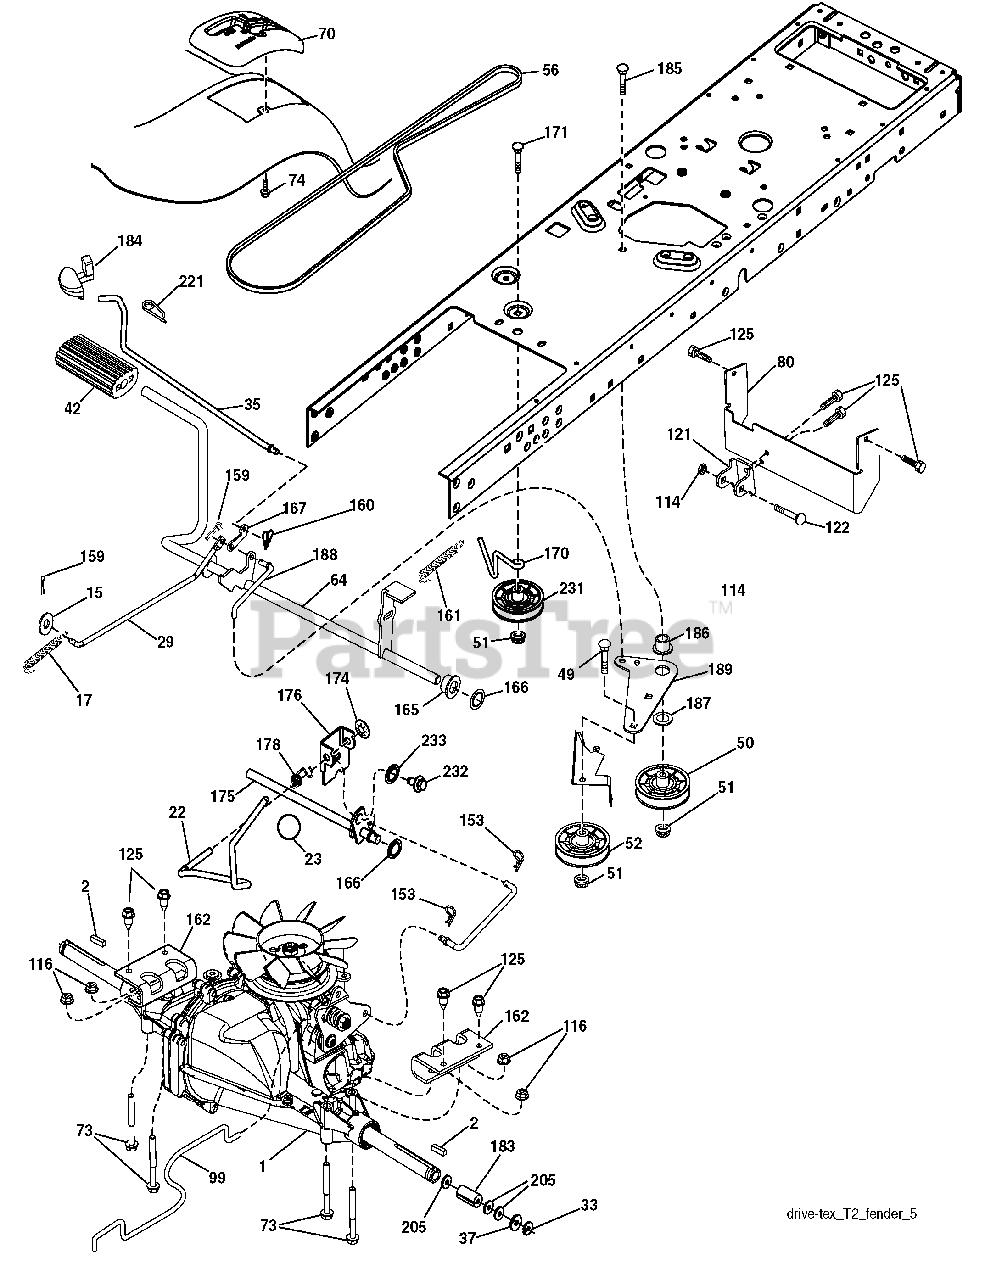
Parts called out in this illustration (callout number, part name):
1	Transaxle, Hydro Gear T2 (See Transaxle Breakdown)
2	Key Square
15	Washer 13/32 x 13/16 x 16 Ga.
17	Spring, Brake
22	Rod Shift
23	Knob
29	Rod, Brake
33	Ring E
35	Rod, Brake, Park
37	Washer 25/32 x 1-1/4 x 16 Ga.
42	Cover, Foot Pedal
49	Bolt
50	Pulley Idler Flat
51	Lock Nut 3/8-16
52	Idler V-Groove 910" Offset
56	V-Belt, Drive
64	Shaft Asm. Pedal Brake Control
70	Console
73	Bolt Hex 5/16-18 Gr. 5
74	Screw 1/4 x 1/2
80	Strap Torque
99	Rod Spring Bypass
114	Nut Lock 5/16-18 unc
116	Nut Lock Hex Flange 5/16-18
121	Bracket Strap Torque
122	Bolt 5/16-18 x 2.50
125	Screw 5/16-18 x 3/4
153	Retainer Spring 1"
159	Pin Cotter 1/8 x 3/4
160	Retainer Clip
161	Spring, Return, Clutch
162	Adapter Transaxle
165	Bushing
166	Nut Push .625
167	Latch Brake Parking
170	Keeper Belt Centerspan
171	Bolt
174	Nut Push
175	Shaft Asm. Shift
176	Arm Clevis Rod Shift
178	Spring Shift
183	Spacer Axle
184	Handle Parking Brake
185	Bolt
186	Spacer Retainer
187	Washer
188	Link Clutch Ground Drive
189	Bellcrank Ground Drive
190	Keeper Bellcrank Ground Drive
205	Washer 25/32 x 1-5/8 x 16 Ga.
221	Retainer Spring Clip
231	Idler V-Groove 1.688" Offset
232	Bolt 7/16-14 x 1 Gr. 5
233	Washer Serrated
279	Link Shift
